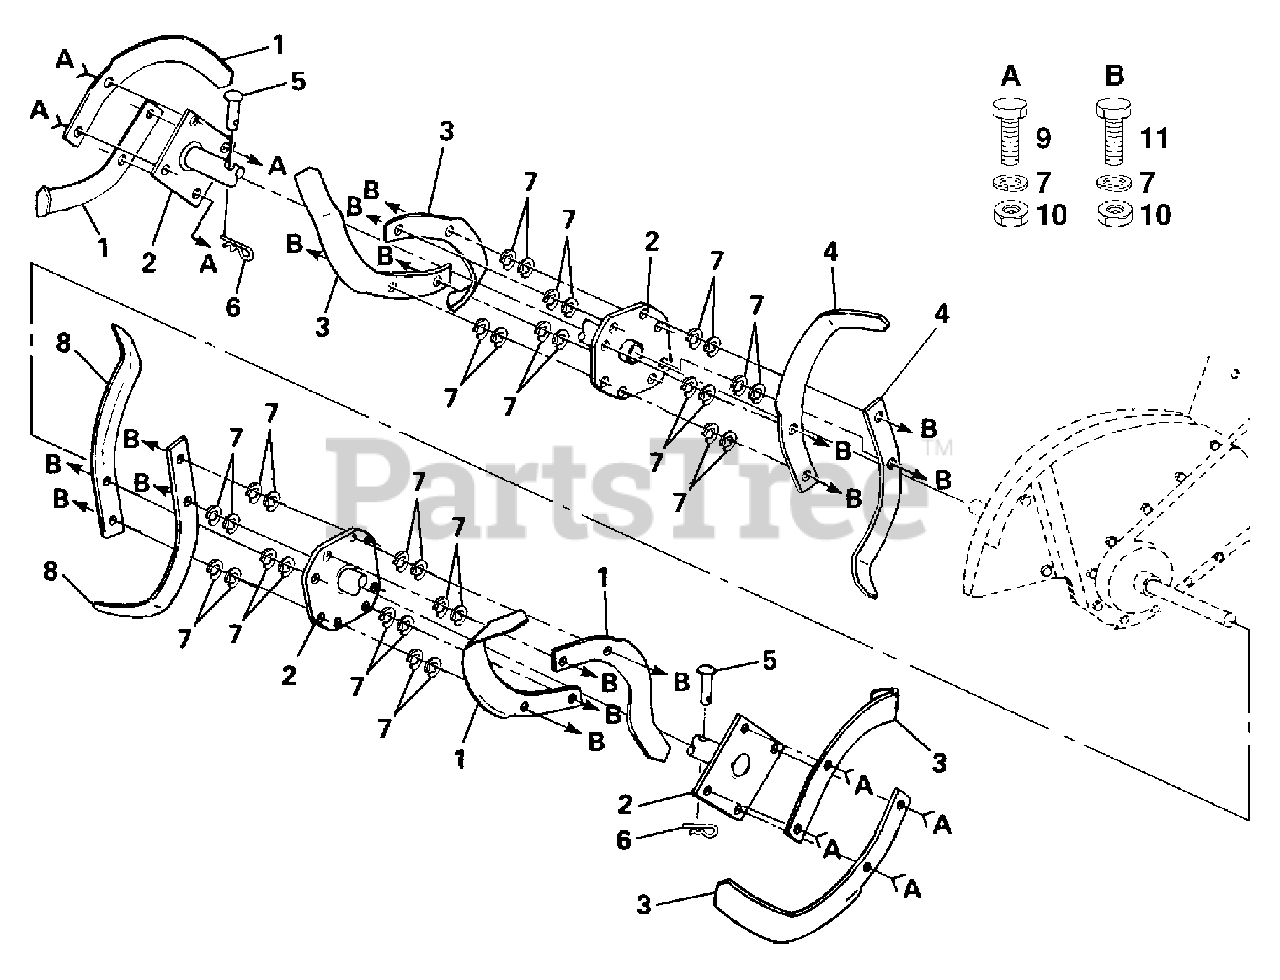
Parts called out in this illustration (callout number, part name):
1	Tine, L.H., 14"
2	Hub Assembly
3	Tine, R.H., 14"
4	Tine, L.H., 14"
5	Rivet, Panhead
6	Clip, Hairpin
7	Washer, Lock 3/8
8	Tine, R.H., 14"
9	Bolt, Hex Head 3/8-24 x 1
10	Nut, Hex 3/8-24
11	Bolt, Hex Head 3/8-24 x 1-1/2
